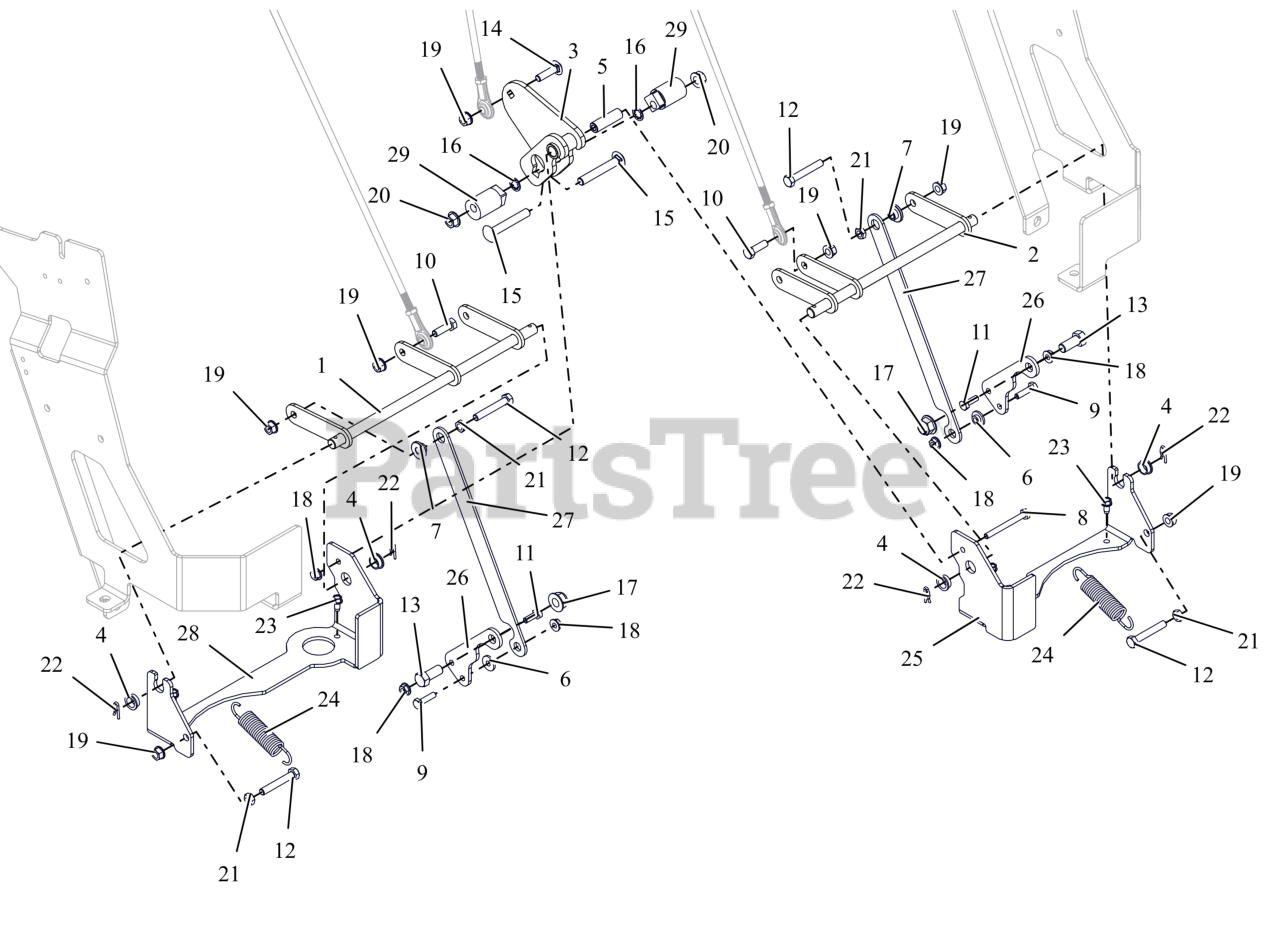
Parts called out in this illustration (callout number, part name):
1	WLDMT, RH LOWER STEERING SHAFT (BLACK)
2	WLDMT, LH LOWER STEERING SHAFT (BLACK)
3	WLDMT, SPEED STOP
4	BSHG,FLANGE .500X.625X.270X.75
5	BSHG, SLV .265X.505X1.665
6	BSHG-FLG .265X.437X.250X.750
7	BSHG-FLG .32X.500X.344X.880
8	BLT, HEX 0.25-20X2.5 GR8 ZCC
9	BLT,HEX .25-20X1.00 G5 ZCC
10	BLT,HEX .31-18X1.00 G5 ZCC
11	BLT, HEX .25-20X.75 G5 ZCC
12	BLT, HEX .31-18X2.00 G5 ZCC
13	BLT, HEX 0.4375-14X1 GR5 ZCC
14	BTL,RHSSN .313-18 X 1.25 G5 ZCC
15	BLT, RHSSN.38-16X2.50 G5 ZCC
16	WSHR-LK .38 INT STAR YWZC
17	NUT,NYL-FLG .44-14 GF ZCC
18	NUT-LK-CTR-FLG .25-20 ZC120
19	NUT,LK-CTR-FLG .31-18 GF ZCC
20	NUT-LK-CTR-FLG .375-16 GF ZCC
21	NUT-JAM .312-18 G2 ZCC
22	CLIP, SPRING
23	SCR-TAP .25-20X.50 HWH ZCC
24	SG-TENS .105X.812X3.88 WLD 15
25	BRKT, LOWER STEERING - LH
26	PLATE, TRANSAXLE ADAPTER (BLACK)
27	LINK, STEERING (BLACK)
28	BRKT, LOWER STEERING - RH
29	ECCENTRIC - .390X1.000X1.750
